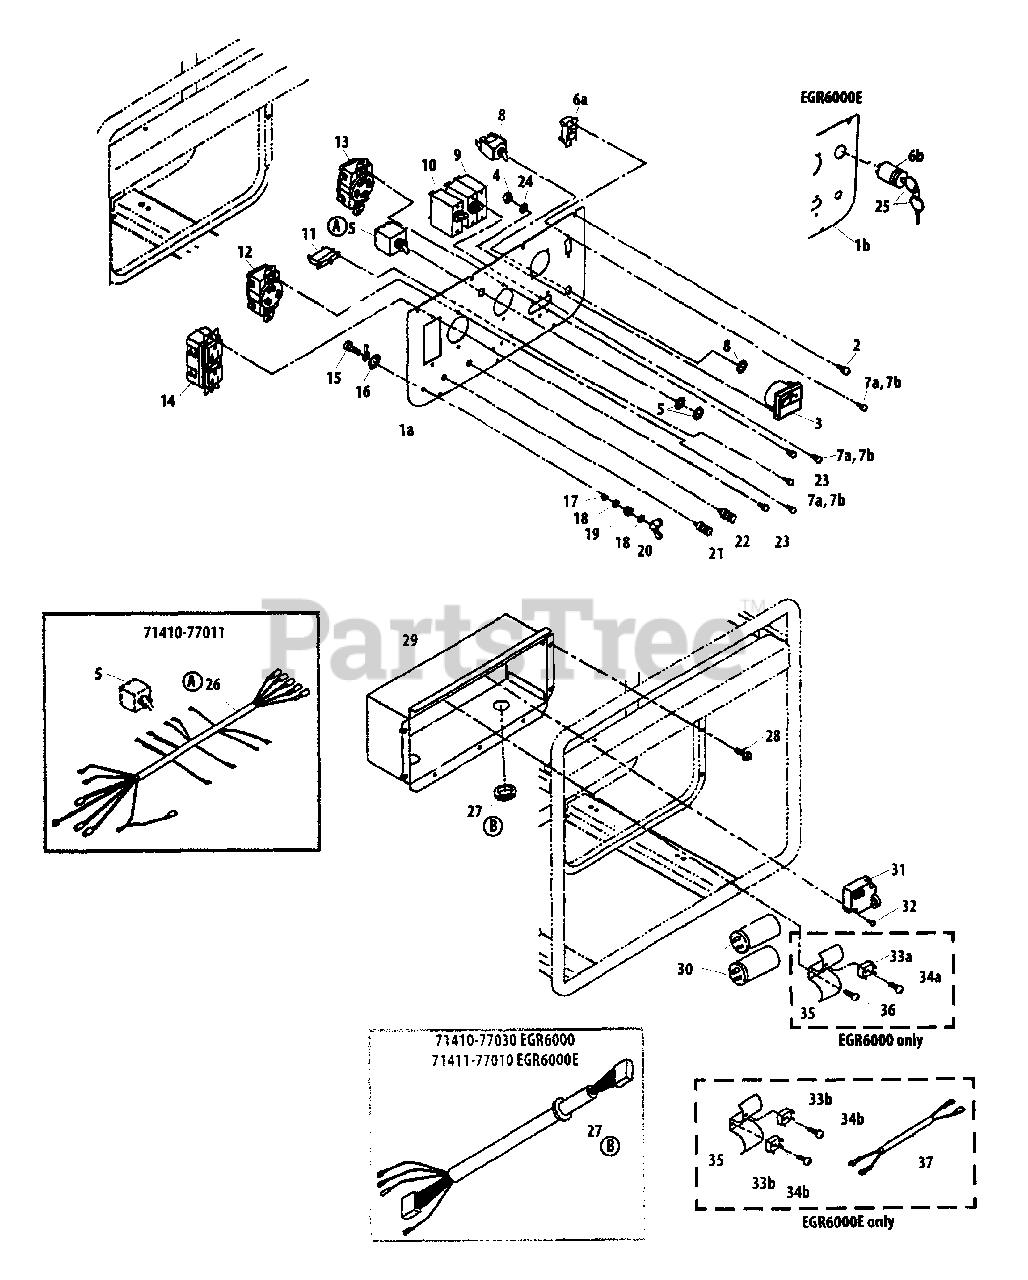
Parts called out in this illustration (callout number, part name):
1A	CONTROL PANEL
1B	CONTROL PANEL
2	SCREW - 4X12
6A	SWITCH
6B	STARTER SWITCH
7A	SCREW
7B	SCREW
9	CIRCUIT PROTECTOR
10	CIRCUIT PROTECTOR
11	CIRCUIT PROTECTOR
12	OUTLET - 120V
13	OUTLET - 220V
14	OUTLET - 120V
15	SCREW - 5X16
16	WASHER - TOOTH
18	LOCKWASHER
21	TERMINAL POST
22	TERMINAL POST
23	SCREW
24	LOCKWASHER
26	WIRING HARNESS
27	GROMMET
29	CONTROL BOX ASSY
30	CONDENSER
31	PRINT CIRCUIT
32	SCREW - 6X20
33A	RECTIFIER
33B	RECTIFIER
34A	SCREW - 4X25
34B	SCREW - 4X25
35	BRACKET, CONDENSER
36	SCREW - 4X14
37	WIRING HARNESS
71410-77011	WIRING HARNESS ASSY
71410-77030	WIRING HARNESS
71411-77010	WIRING HARNESS/RECOIL
